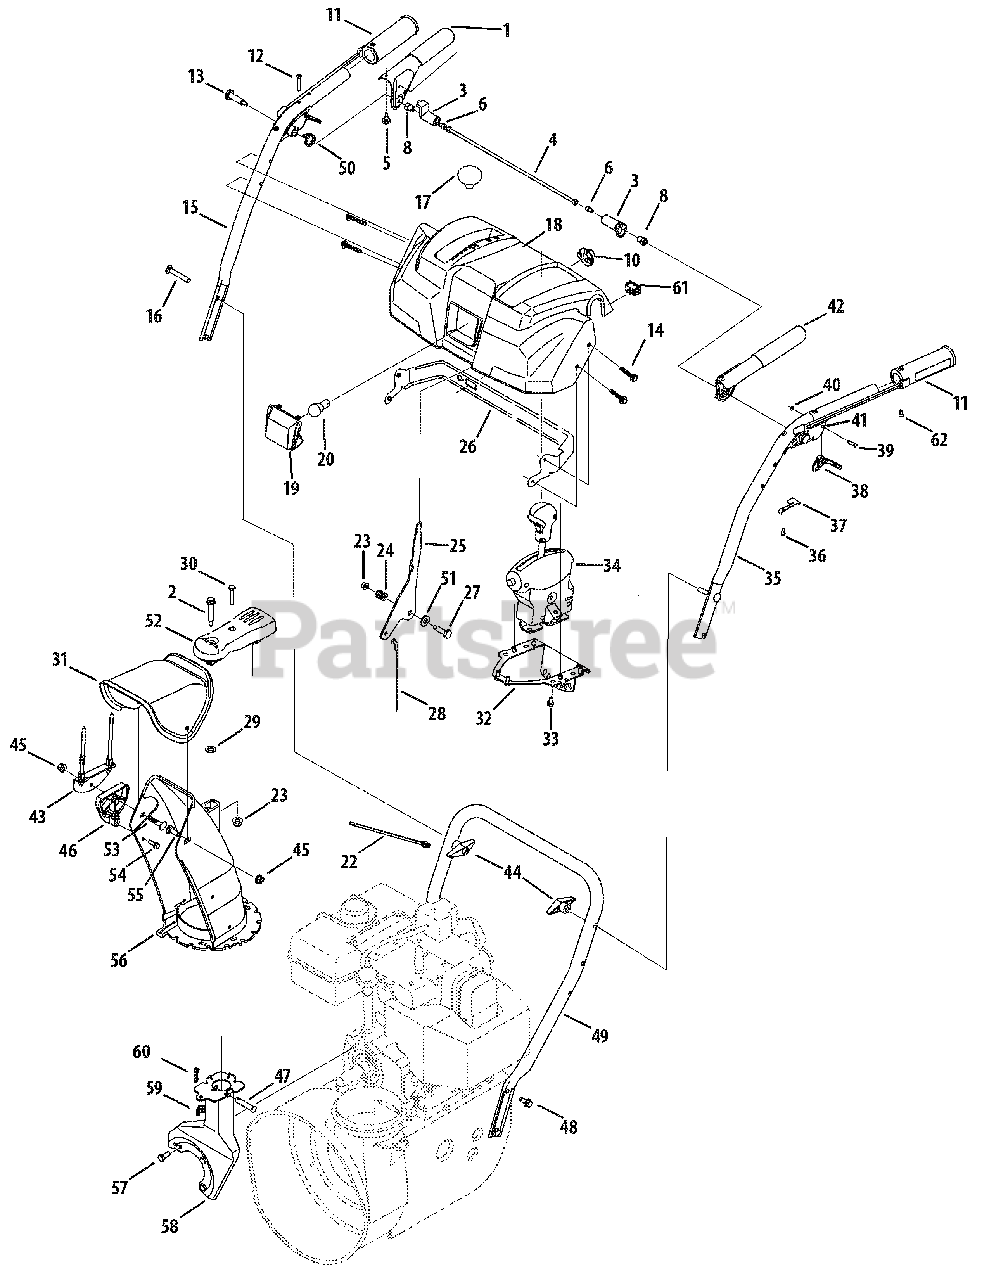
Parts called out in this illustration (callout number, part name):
1	Handle Engagement Assembly RH
2	Flange Shoulder Screw
3	Lock Plate
5	Rubber Bumper
6	Screw, 1/4-20 x.375
7	Clutch Lock Cam
8	Shoulder Nut, 1/4-20
10	Light Socket
11	Heated Handle Grip
12	Screw, #10-24 x 0.375
13	Shoulder Screw, 1/4-20 x 1.345
14	Screw, 1/4-20 x 1.625
16	Carriage Screw, 5/16-18 x 2.25
17	Shift Knob
18	Handle Panel (Includes Ref. #19)
20	Lamp
21	Handle Clutch Lock - RH
22	Cable Tie
23	Flange Lock Nut, 1/4-20
24	Compression Spring
27	Shoulder Screw
28	Speed Selector Cable
29	Flat Washer, .25 x .630 x .0515
30	Screw, #10-16 x .500
31	Upper Chute
33	Hi-Lo Screw, 1/4-15 x 0.5
34	4-Way Chute Control(TM) Assembly
36	Screw, #8-16 x 0.50
37	Clutch Lock Spring
38	Steering Control
41	Handle Clutch Lock - LH
42	Handle Engagement Assembly LH
44	Wing Knob
45	Flange Lock Nut, 5/16-18
46	Chute Tilt Cable Guide
50	Torsion Spring
51	Flat Washer
52	Joystick Pulley Cover
53	Carriage Bolt, 5/16-18 x 1.50
54	Hi-Lo Screw, 1/4-15 x .75
55	Carriage Bolt, 5/16-18 x 1.0
56	Lower Chute
57	Hex Screw, 5/16-24 x .750
60	Bow Tie Cotter Pin
61	Heated Grip Switch
